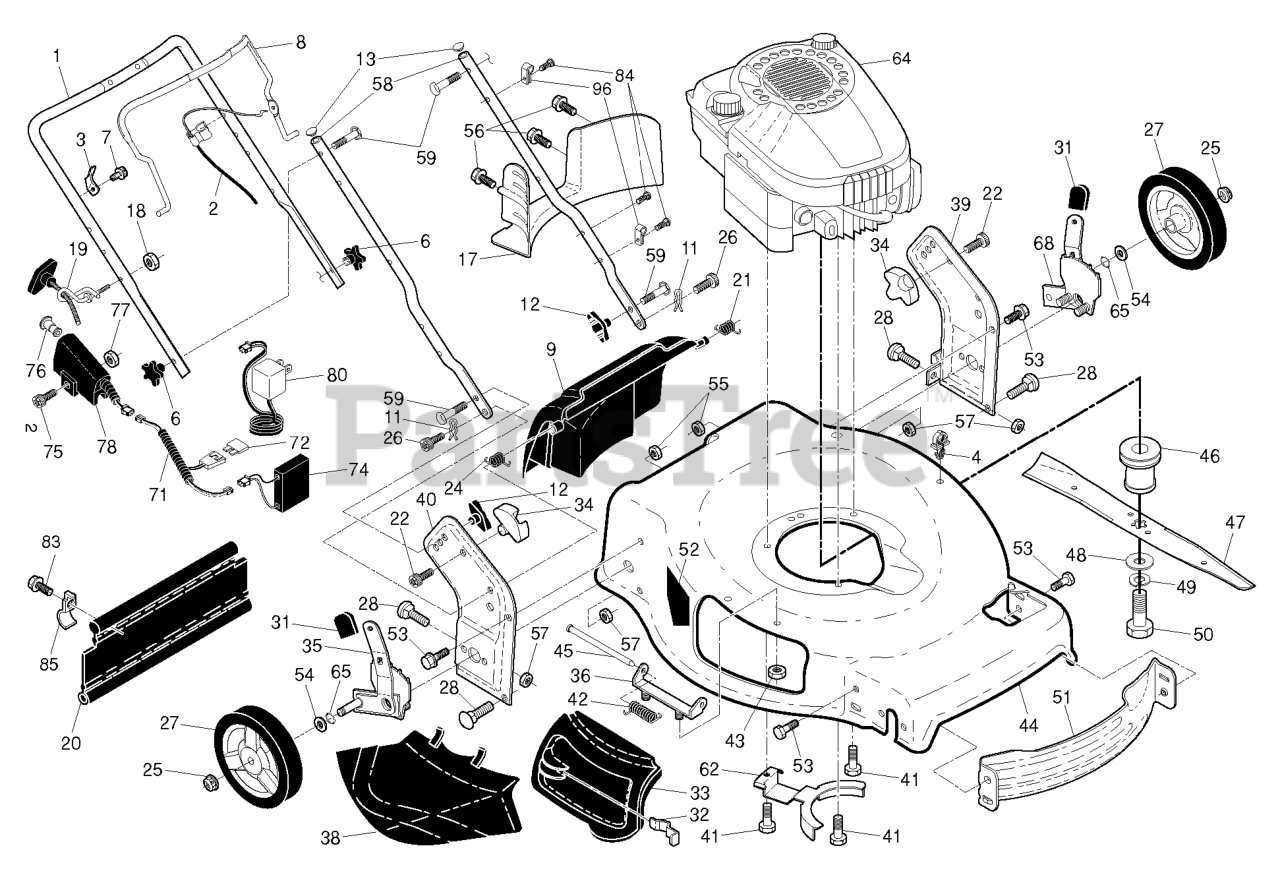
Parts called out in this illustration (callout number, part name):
1	HANDLE.UP.PNT
2	CABLE.ASM.ZONE.CONTROL
3	BRACKET.UPSTOP.RT
6	KNOB.HANDLE.PLASTIC.STAR.BLACK
8	BAIL.OVER.MOLD.ERGO.MZR.ORANGE
9	DOOR.REAR.ASM.22+.HUSQ.FG/RGD
11	COTTER.HAIRPIN.DOOR/HANDLE.PIV
12	KNOB, DEFLECTOR
13	PLUG.PLASTIC.7/8".14-20.GAUGE
17	BAFFLE.22PLUS.FGD.REAR.
18	NUT
19	RB GUIDE.ROPE.STD.BLK.ZIN WSL
20	SKIRT.REAR.22PLUS.RGD/FGD.NEW
21	SPRING.LH.BLACK
22	SCREW.PAN.HEAD.#10
24	SPRING.RH.GRAY
25	NUT.HEX.FLANGE.3/8-16.LO(3 2)
26	SCREW,DOOR/HANDLE.PIVOT
27	WHEEL & TIRES ASSY, FRONT
28	BOLT
31	KNOB.ADJUSTER.REAR.RED
32	LATCH.DOOR.ZINC
33	DOOR.MULCH.22 PLUS.HUSQ.GREY
34	BRACKET.GRASSBAG.ATTACHING.BLK
35	ADJUSTER.ASM.9POS.LW.RR/RGD.
36	BRACKET.ASM.HINGE.21.FWGD.
38	DEFLECTOR.CLIPPING.22.BLACK
39	BRACKET.ASM.HNDL.LT.22+.GREY
40	BRACKET.ASM.HNDL.RT.22+.GREY
41	BOLT 3/8-16X1-1/8
42	SPRING.TORSION
43	NUT.HEX.FLANGE.1/4
44	HOUSING.22+.FWD.MC.ZWO.ORANGE.
45	ROD.HINGE.21
46	ADPTER.BLAD.25M.VS.22PLU.STAR
47	BLADE.22+4N1.2PIN.5STAR.(P07)
48	WASHER,HARDEN
49	LOCKWASHER
50	SCREW, HEX HD 3/8-24 X 1-3/8
51	BAFFLE.FRONT.22.PLUS
52	DANGER DECAL
53	BOLT.5/16HEX.WHS.HD
54	WASHER.FLAT.1/2
55	NUT.HEX.FLANGE.1/4
56	SCREW.HX.13X.750
57	NUT.FLANGE.5/16
58	HANDLE.LOWER.22+BT.2PC.GRY
59	BOLT, HANDLE 5/16-18X1.75
62	BRACKET.ENG/BELTKEEPER
65	O-RING..070X.487.NEOPRENE
68	ADJUSTER.ASM.9POS.LW.RL/RGD.FR
71	HARNESS.WB.BATTERY.FGD.22+
74	BATTRY.12VLT.22+.FGD.W/PAD AGM
75	BOLT.M6-1X40.T30
76	BUTTON.KEY.CYLINDER.BLACK
77	NUT.M6-1 NYLOC
78	RP CONTROLSH.BUTTON.START.22"
80	RP CHARGER.12V.0.1A
83	TAPPING SCREW
84	FASTENER.PUSH.O.250X0.783
85	BRACKET.SKIRT.22+.BZP
96	CLIP.CABLE.BLK
